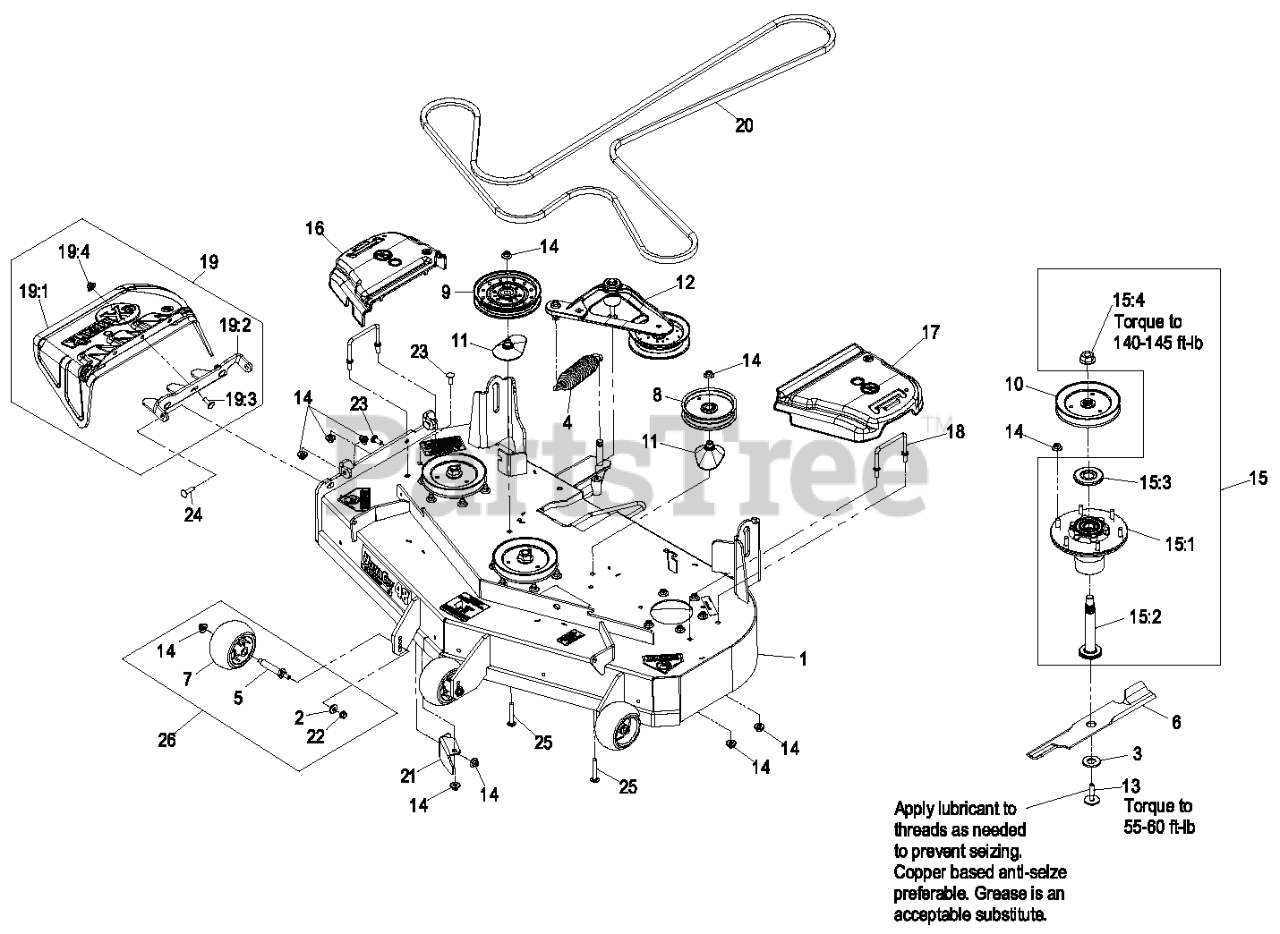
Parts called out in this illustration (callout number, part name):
2	WASHER-BELLEVILLE
3	WASHER-BLADE DRIVE
7	ROLLER-SCALP, ANTI
8	PULLEY-IDLER
10	SHEAVE,BLADE DRIVE 5.90
11	SPACER-PULLEY
13	BOLT-BLADE, SEM
14	Nut-Nyloc 3/8-16 Flg
15:1	ASM,CUTTER HSG WITH BEARI
15:2	SPINDLE,HEX PILOT 5.5" DE
15:3	GUARD,BEARING TOP .989
15:4	NUT-FLANGE
16	COVER-BELT, RH
17	COVER-BELT, LH
18	WIREFORM-COVER
19	ASM,DISCHARGE CHUTE
19:1	CHUTE,DISCHARGE
19:2	BRACKET,DISCHARGE CHUTE
19:3	SCREW-CARR
19:4	Nut-Nyloc 3/8-16 Flg
21	BAFFLE,DISCHARGE
22	NUT-HHF, WHIZ
23	SCREW-CARR
24	Bolt-Carriage 3/8-16 X 1 1/4
25	SCREW-CARR
27	Asm, Complete Deck
